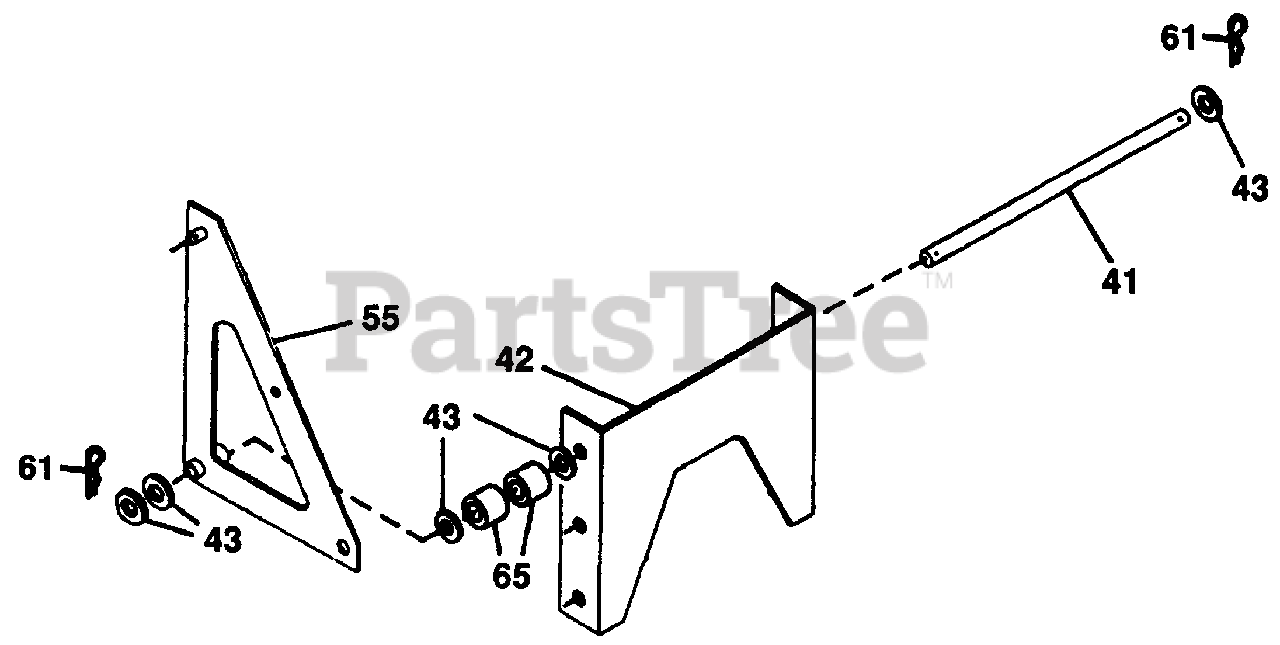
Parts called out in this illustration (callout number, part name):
41	SHAFT, SNOWBLOWER MOUNTING
42	PIVOT SUPPORT
43	WASHER, .656X1.312X.095
55	LIFT BELLCRANK
61	PIN, HAIR .141X2.75
65	BUSHING, .750X1.002X.625
